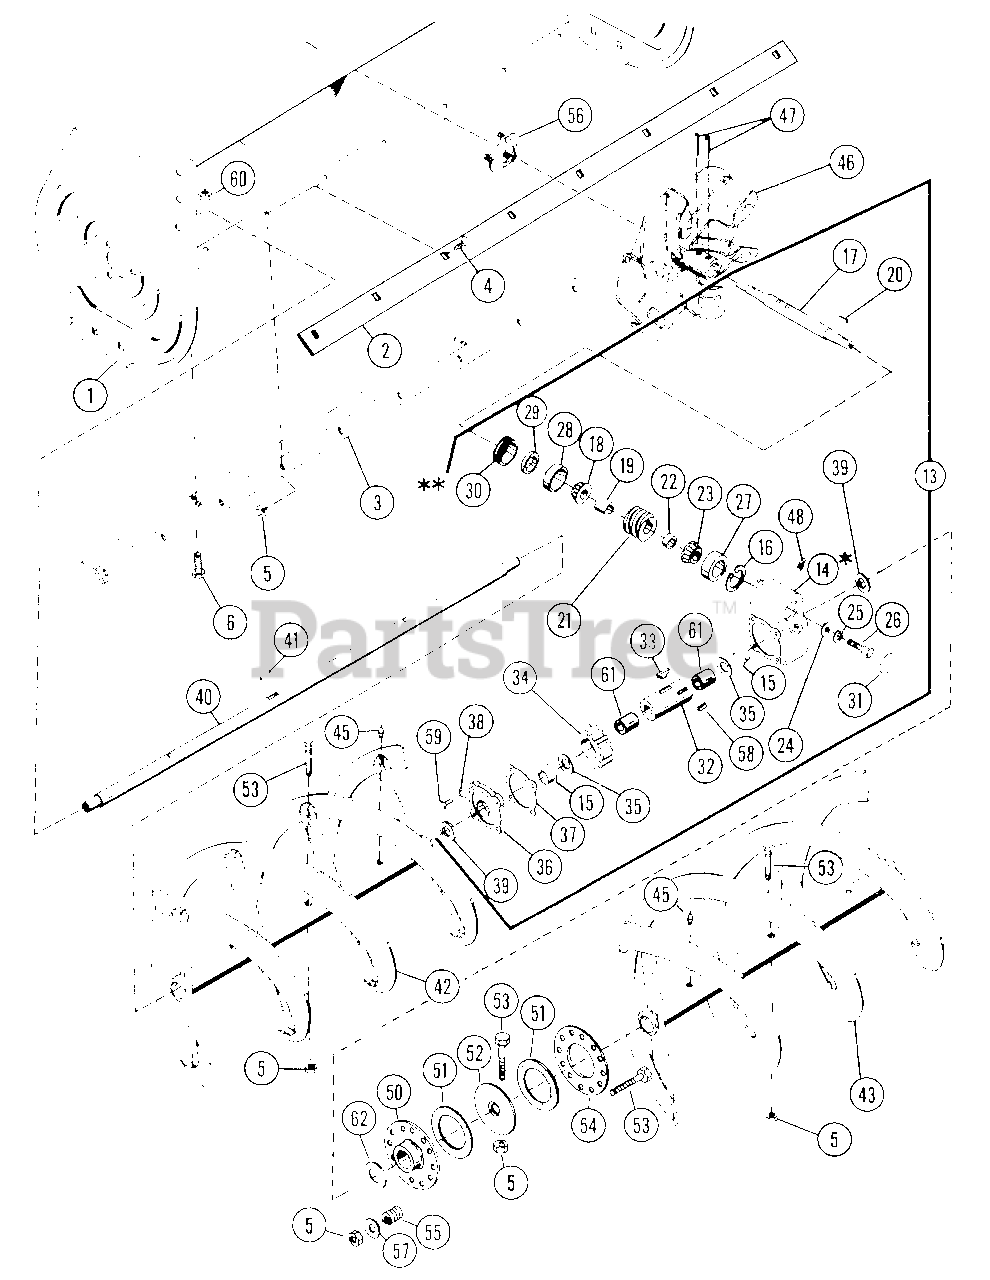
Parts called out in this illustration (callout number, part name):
1	48-INCH SNO THRO HOUSING
2	SCRAPER BLADE
3	SCRAPER BLADE BRACE
4	BOLT, CARRIAGE 5/16-18X.875
5	NUT, LOCK 5/16-18
6	BOLT, HEX 3/8-16X.75
13	BLOWER GEARCASE
14	GEAR CASE
15	BUSHING, FLANGE 1.62X1.87X11
16	RING, SNAP INTERNAL 1.781
17	SHAFT, WORM
18	BEARING, CONE
19	BEARING SPACER
20	KEY, STRAIGHT SAE 1035
21	WORM
22	SPACER, BEARING
23	BEARING, CONE
24	WASHER, FLAT .344X.688X.065
25	WASHER, LOCK 3/8 SP HEAVY
26	BOLT, HEX 5/16-18X.75
27	BEARING CUP
28	BEARING CUP
29	SEAL
30	ADJUSTMENT PLUG
31	CAP, DUST
32	GEARCASE SHAFT
33	KEY, FEATHER
34	GEAR, WORM
35	WASHER, 1.625X2.50X.012
36	COVER, GEARCASE
37	GASKET
38	WASHER, LOCK 1/4 EXT. TH. TYA
39	SEAL
40	48" RAKE SHAFT
42	RIGHT RAKE
43	LEFT RAKE
45	FITTING, LUBE 1/4-28
46	FAN
47	PIN, ROLL 5/16X1.75
48	PIPE PLUG
50	DRIVER
51	FRICTION DISC
52	DRIVER PLATE
53	BOLT, HEX 5/16-18X2.00
54	PRESSURE PLATE
55	SPRING, COMPRESSION
56	BEARING, FLANGE
57	WASHER, FLAT
58	KEY, STRAIGHT
59	BOLT, HEX 1/4-20X.875
60	NUT, LOCK 3/8-16
61	BUSHING, SLEEVE
62	WASHER
